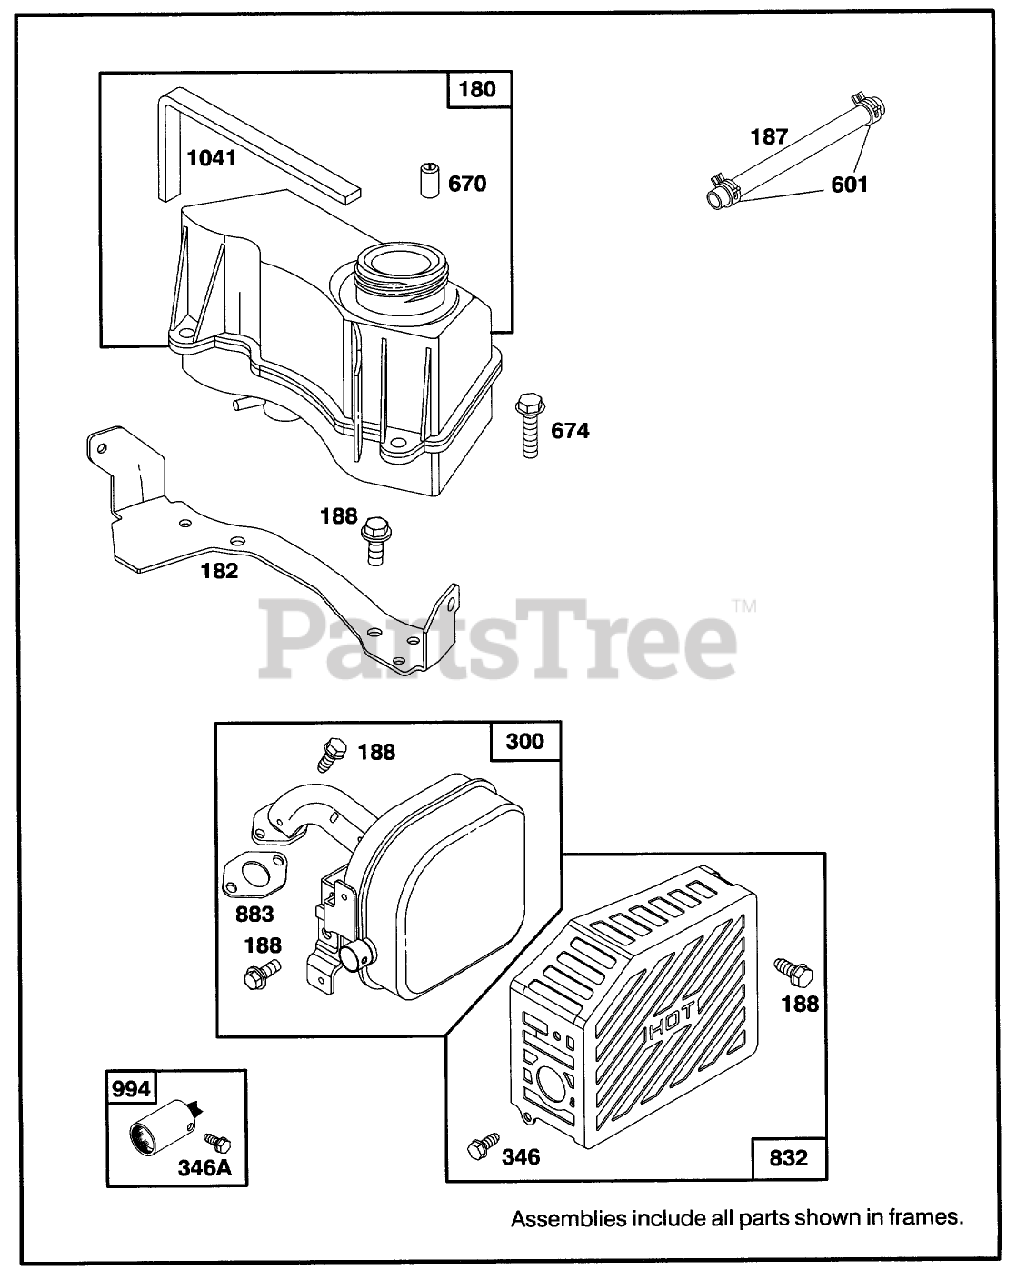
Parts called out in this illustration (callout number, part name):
180	TANK ASSY - FUEL
188	SCREW - SEM
300	MUFFLER - EXHAUST
346	SCREW - SELF-TAPPING
601	CLAMP - CL PIPE
670	SPACER
674	SCREW - HEX HEAD
